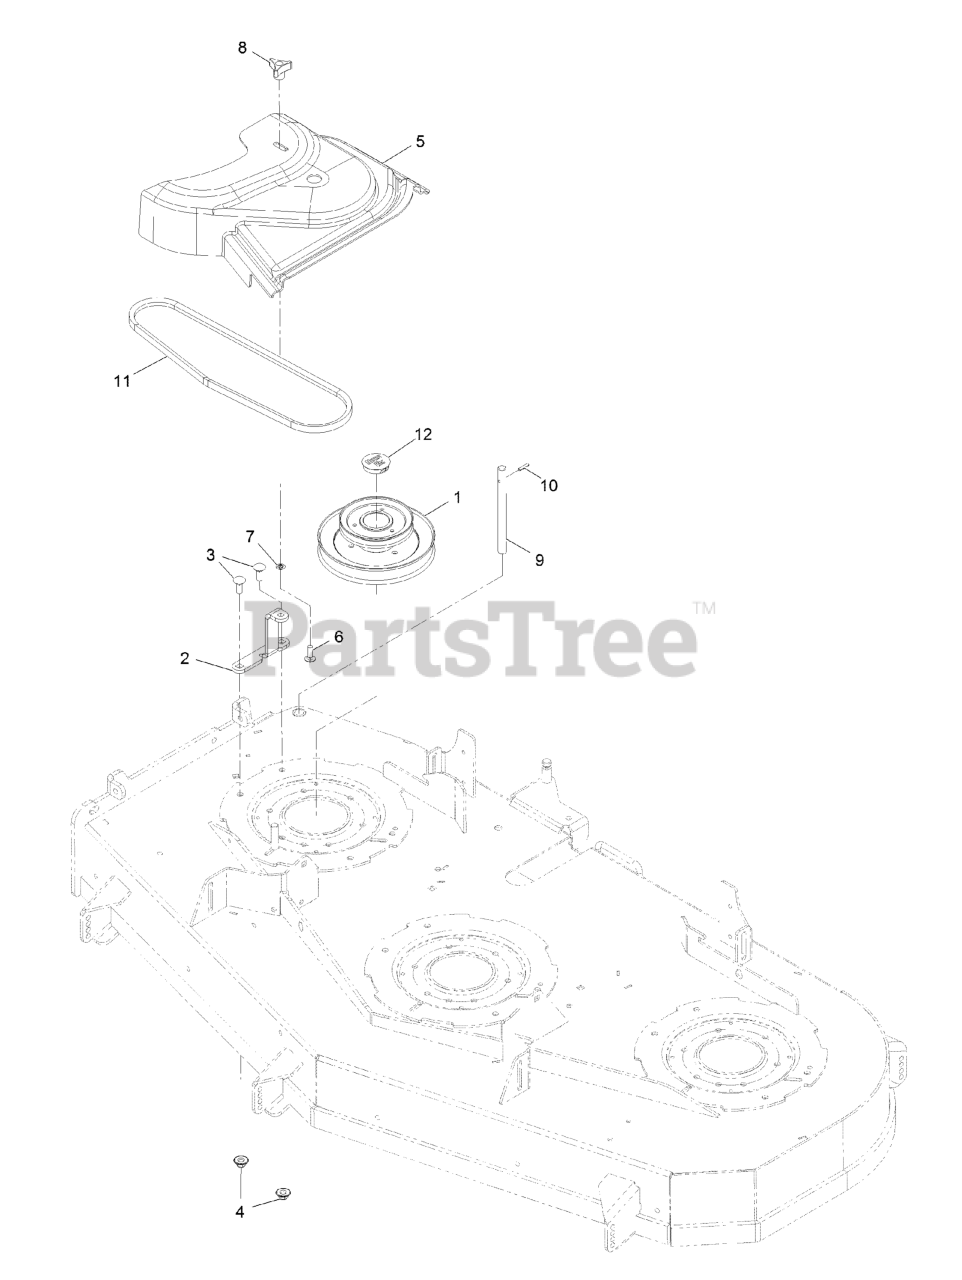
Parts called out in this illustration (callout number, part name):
1	JACKSHAFT,UV DRIVE 604 SPLINED
2	BRACKET-BELT COVER
3	BOLT-CARR
4	Nut-Nyloc 3/8-16 Flg
5	COVER-BELT, UV 60 ENTRY
6	BOLT-CARR
7	RING-RETAINING, BOLT
8	KNOB-3 PRONG
9	SHAFT-CATCHER, GRASS
10	PIN-ROLL
11	V-BELT (17569)
12	PLUG, BLACK NYLON 1.75
